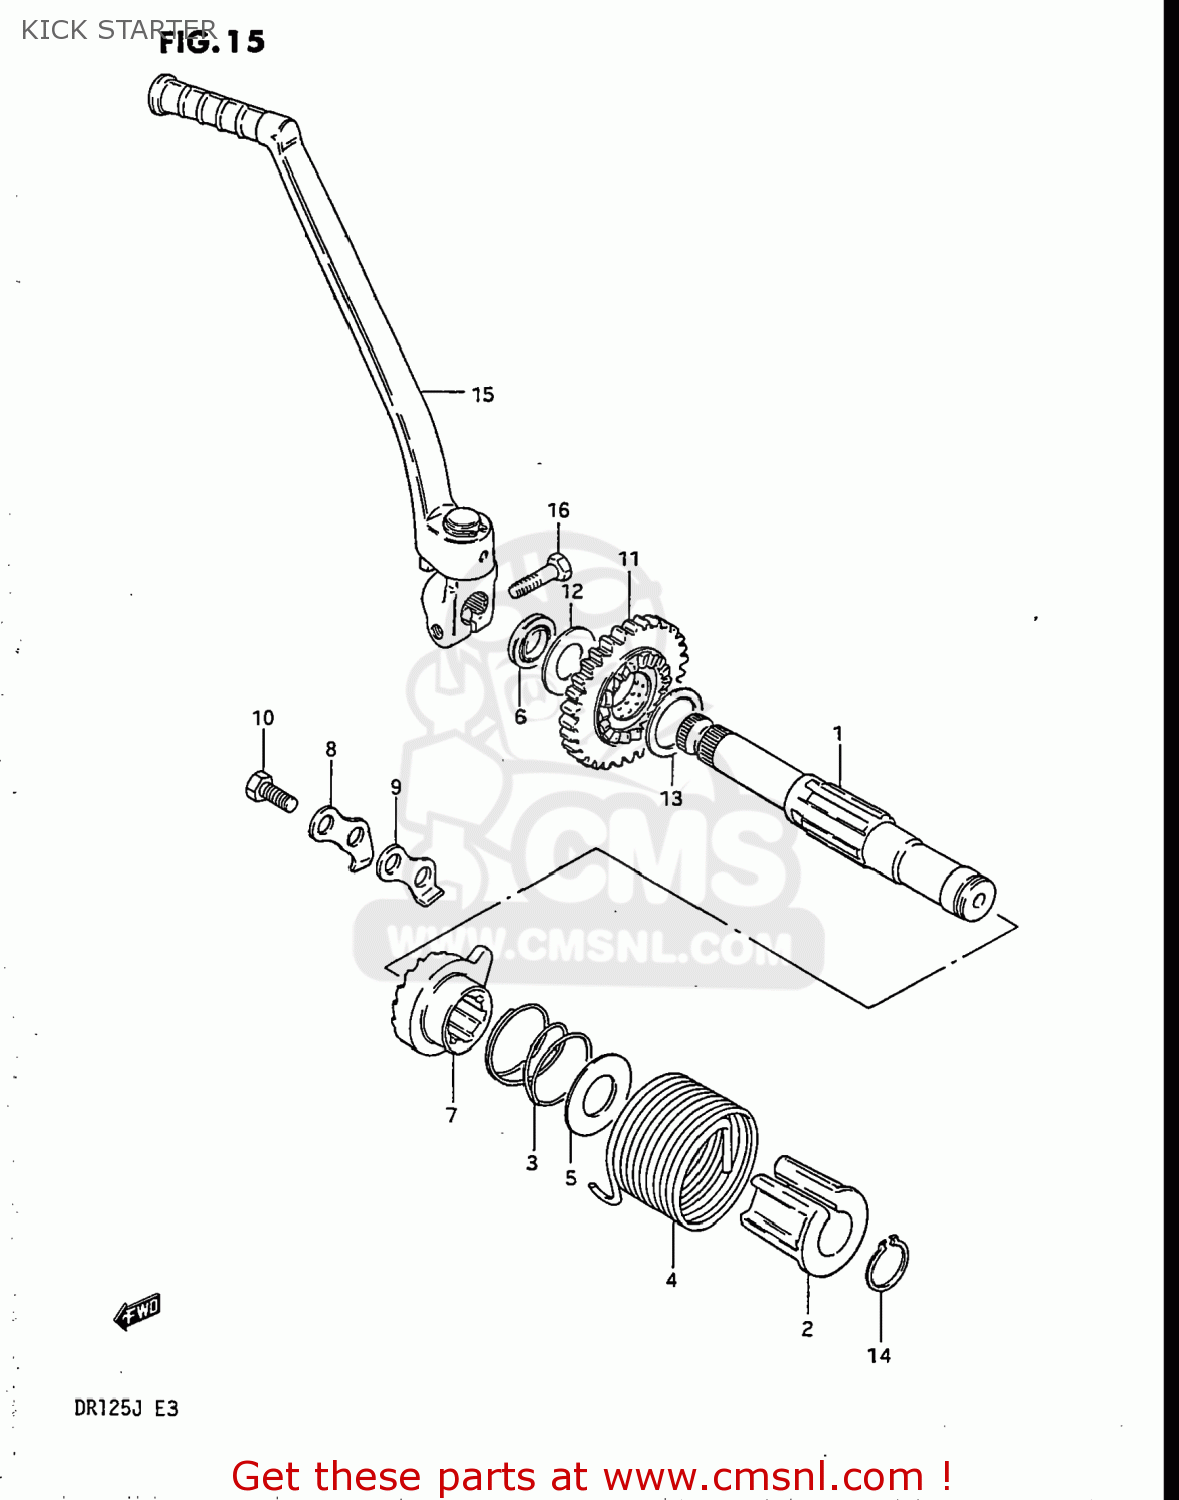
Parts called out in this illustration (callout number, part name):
1	SHAFT,KICK STARTER
2	GUIDE,KICK STARTER SFT SPRING
3	SPRING
4	SPRING
5	WASHER
6	SEAL,OIL(16X24X5)
7	STARTER,KICK
8	GUIDE,KICK STARTER
9	STOPPER,KICK STARTER
10	BOLT
11	GEAR,KICK STARTER DRIVE
12	WASHER(16X30X1)
13	WASHER
14	CIRCLIP
15	LEVER ASSY,KICK STARTER
16	BOLT 8X25
